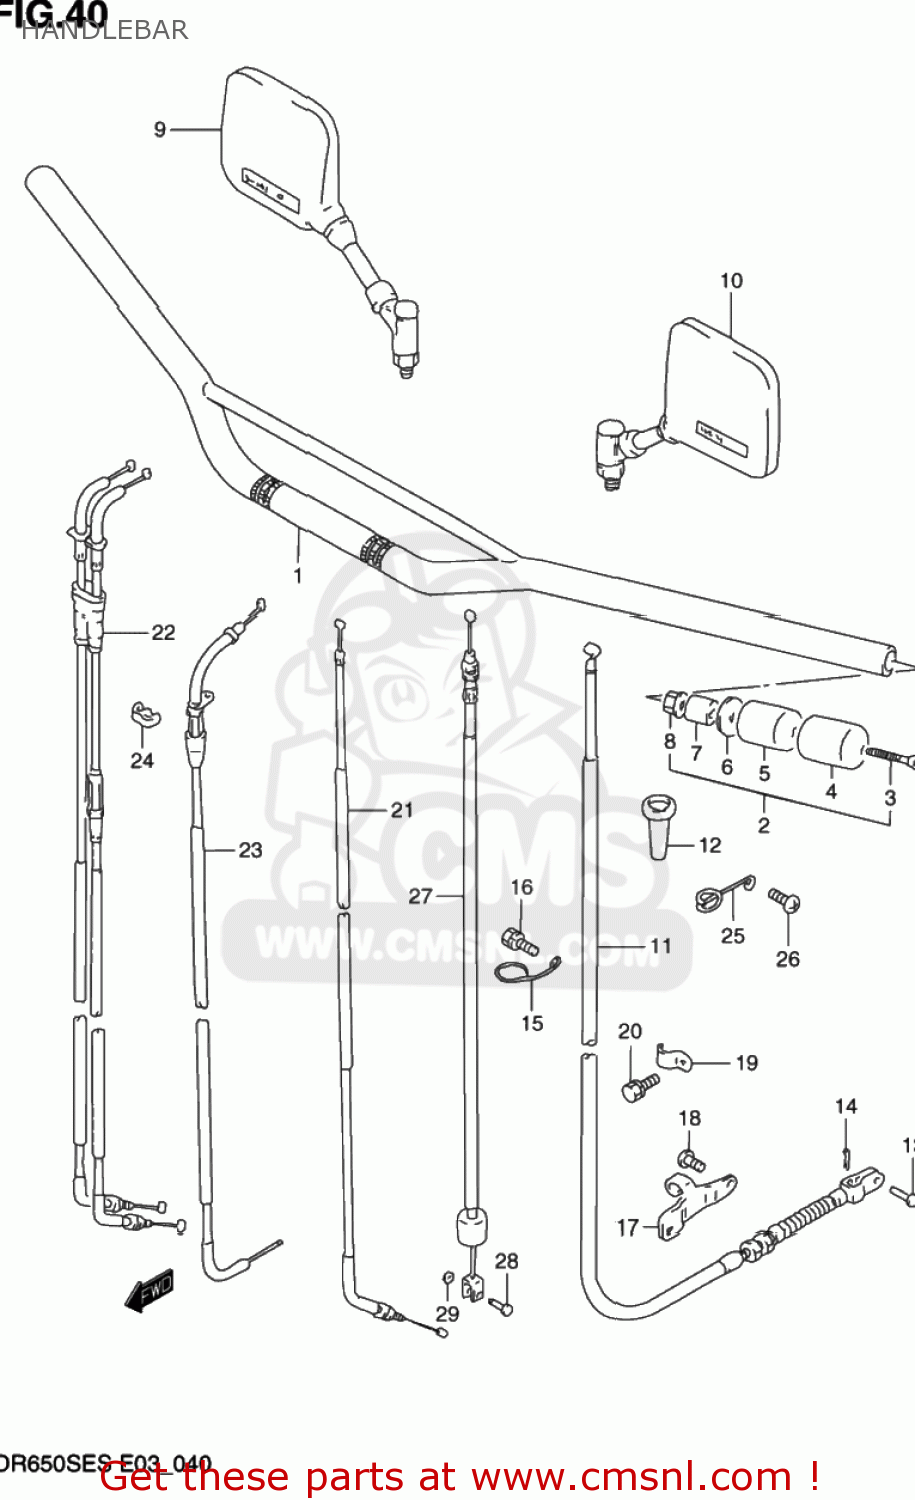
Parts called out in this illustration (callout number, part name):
1	HANDLEBAR
2	BALANCER SET,HANDLEBAR
3	SCREW
4	CAP,BALANCER
5	BALANCER,HANDLE
6	SPACER,BALANCER
7	EXPANDER,HANDLE BALANCER
8	NUT
9	MIRROR ASSEMBLY,REAR VIEW
10	MIRROR ASSEMBLY,REAR VIEW
11	CABLE ASSY,CLUTCH
12	BOOT,CLUTCH CABLE
13	PIN(L:13)
14	PIN
15	GUIDE
16	BOLT
17	STOPPER,CLUTCH CABLE
18	BOLT
19	CLAMP
20	BOLT
21	CABLE ASSY,DECOMP
22	CABLE ASSY,THROTTLE
23	CABLE,STARTER
24	CLIP
25	GUIDE,CLUTCH CABLE
26	SCREW
27	CABLE ASSY,DECOMP
28	PIN(4X12.5)
29	E RING
